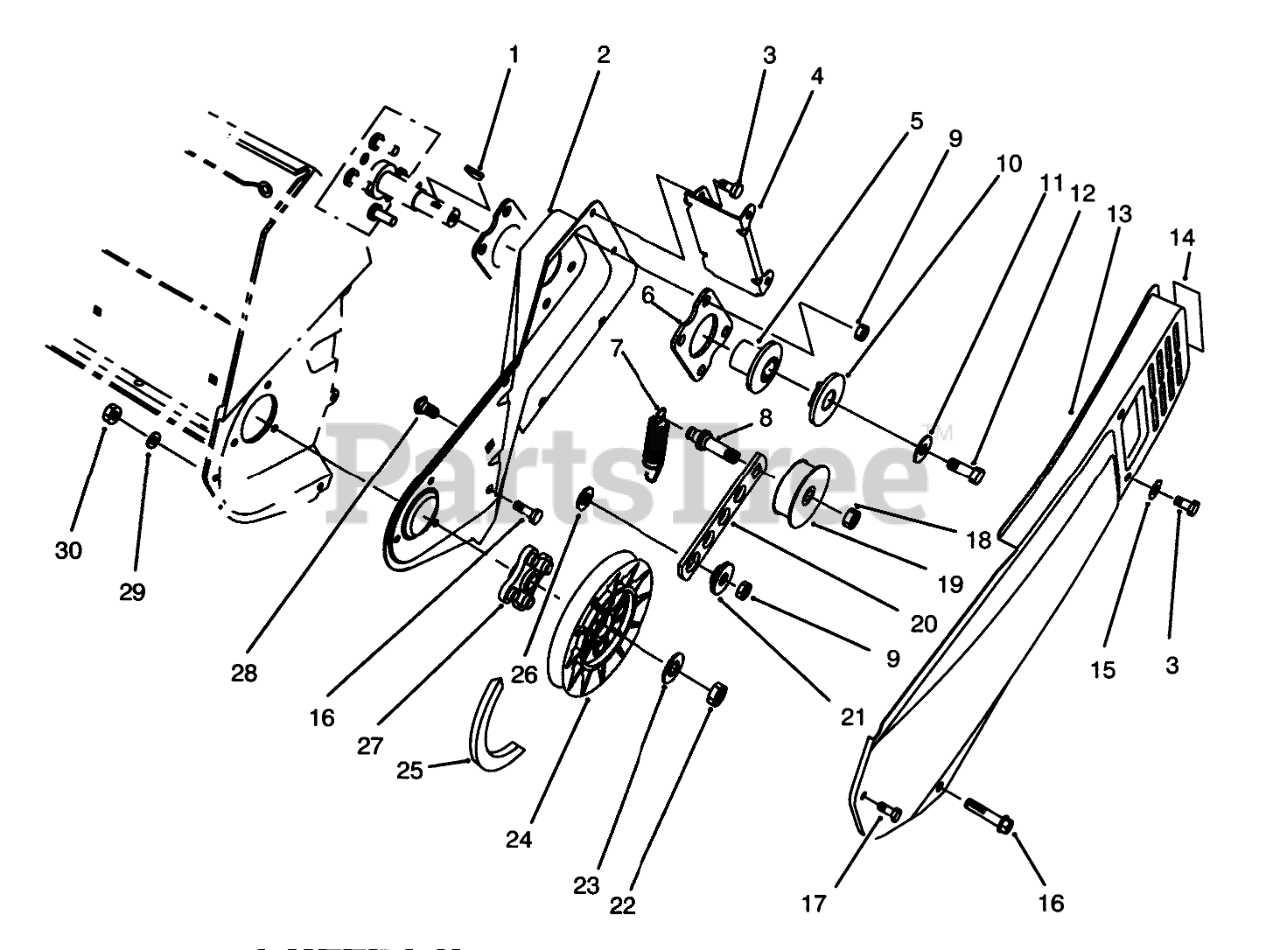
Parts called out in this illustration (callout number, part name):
1	KEY-WOODRUFF
2	Sideplate-LH
3	SCREW-HWH
4	Bracket-Cover
5	Hub-HALF SHEAVE
6	Plate Engine
7	SPRING-EXTENSION
8	PIN-IDLER
9	NUT-LOCK, NI
10	CAP-HALF SHEAVE
11	WASHER-FLAT
12	SCREW-HH
13	Cover-Belt
14	Decal
15	WASHER-FLAT
16	SCREW-PLASTIC
18	NUT-LOCK, NI
19	PULLEY-IDLER
20	ARM-IDLER
21	BUSHING-IDLER
22	NUT-LOCK, NI
23	WASHER-FLAT
24	PULLEY-DRIVEN
25	V-BELT
26	WASHER
28	SCREW-CARR
29	WASHER-FLAT
30	NUT-LOCK, NI
